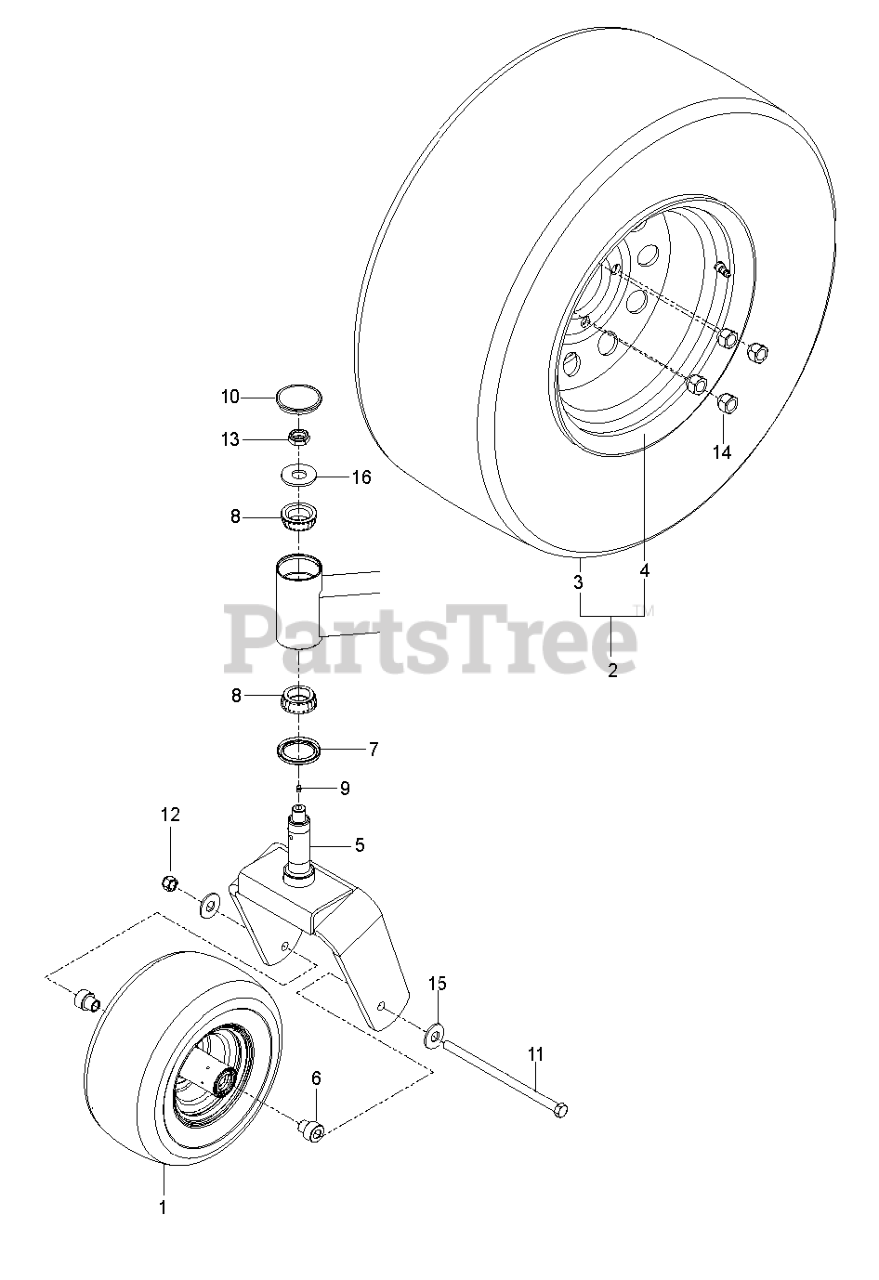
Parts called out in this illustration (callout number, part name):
1	TIRE, 13 X 6.5-6 NO FLAT
2	WHEEL/TIRE.ASM SILV 23X10.5-12
3	TIRE.TURF.MASTER.23X10.5-12
4	RIM, 12 X 8.5, 1.125" NEG OS
5	FORK.CASTER.ORANGE
6	AXLE SPACER
7	SEAL, BEARING
8	CONE, LM67048
11	HEX SCREW 1/2-13 X 9.5 GR5
12	NUT, 1/2-13 HEX FLG NYLOC ZD
13	NUT, 3/4-16 HEX THIN NYLOC ZD
14	WASHER 1/2" FLAT
15	WASHER 1/2" FLAT
16	WASHER, 3/4 HARDENED
